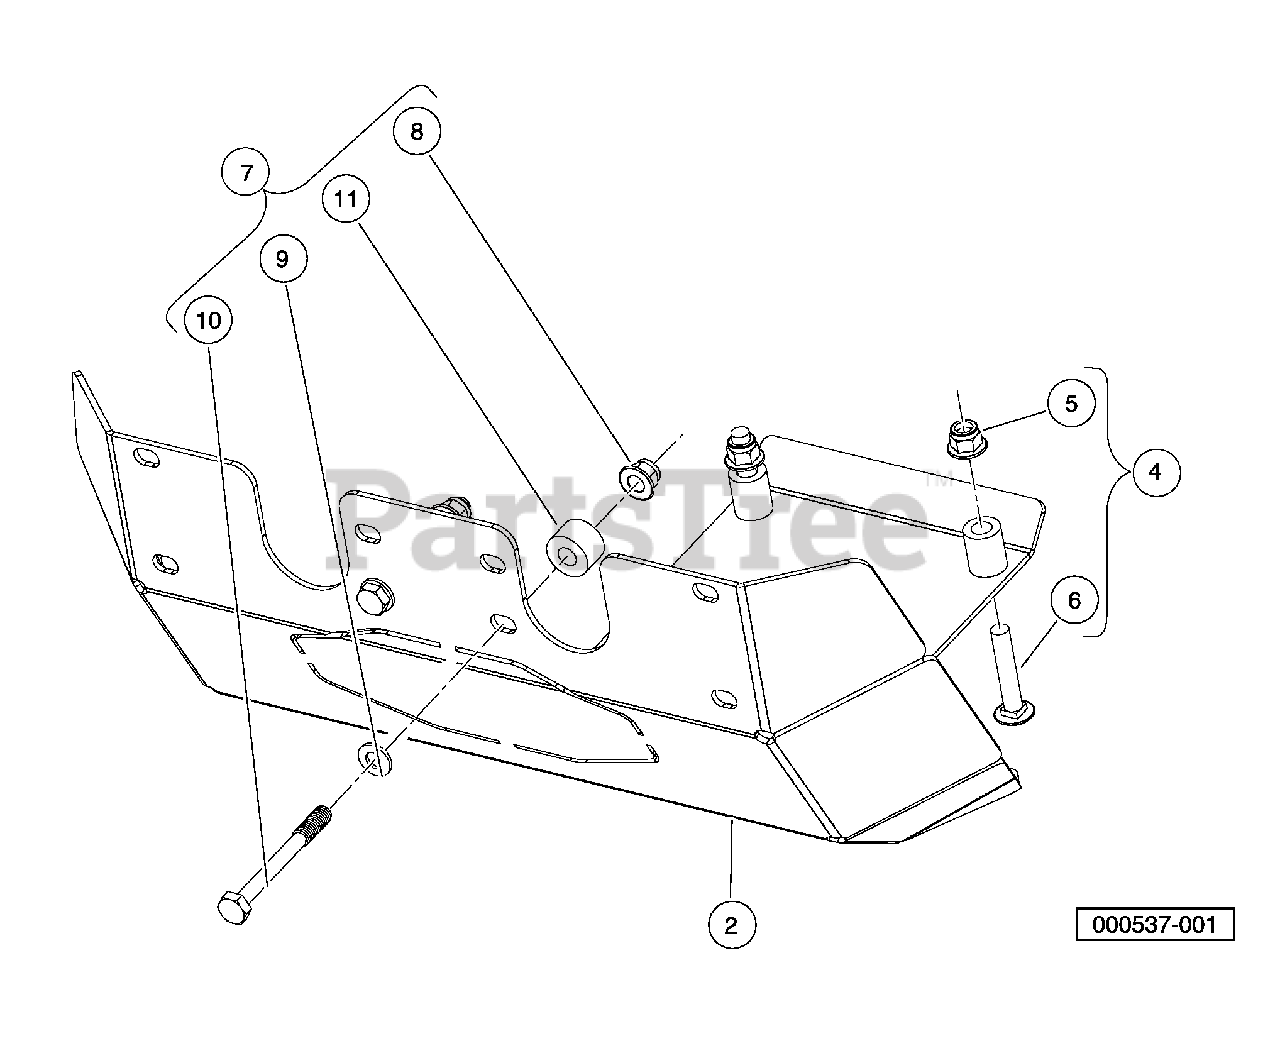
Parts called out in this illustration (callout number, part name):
1	Kit, Skidplate, Front, Steel
2	Skid Plate, Front, Steel
3	Instructions, Front Skidplate
4	Kit, Hardware, Skidplate, Front, A
5	Nut Flg M10 X 1.5 Nylon
6	Bolt, Carriage, M10x1.5x55
7	Kit, Hardware, Skidplate, Front, B
8	Nut Flg M10 X 1.5 Nylon
9	Washer, Hard, M10, Zn-Ni/Blk.
10	Bolt, M10 X 1.50 X 90, Loctite.
11	Spacer, 17mm Long, Skidplate
